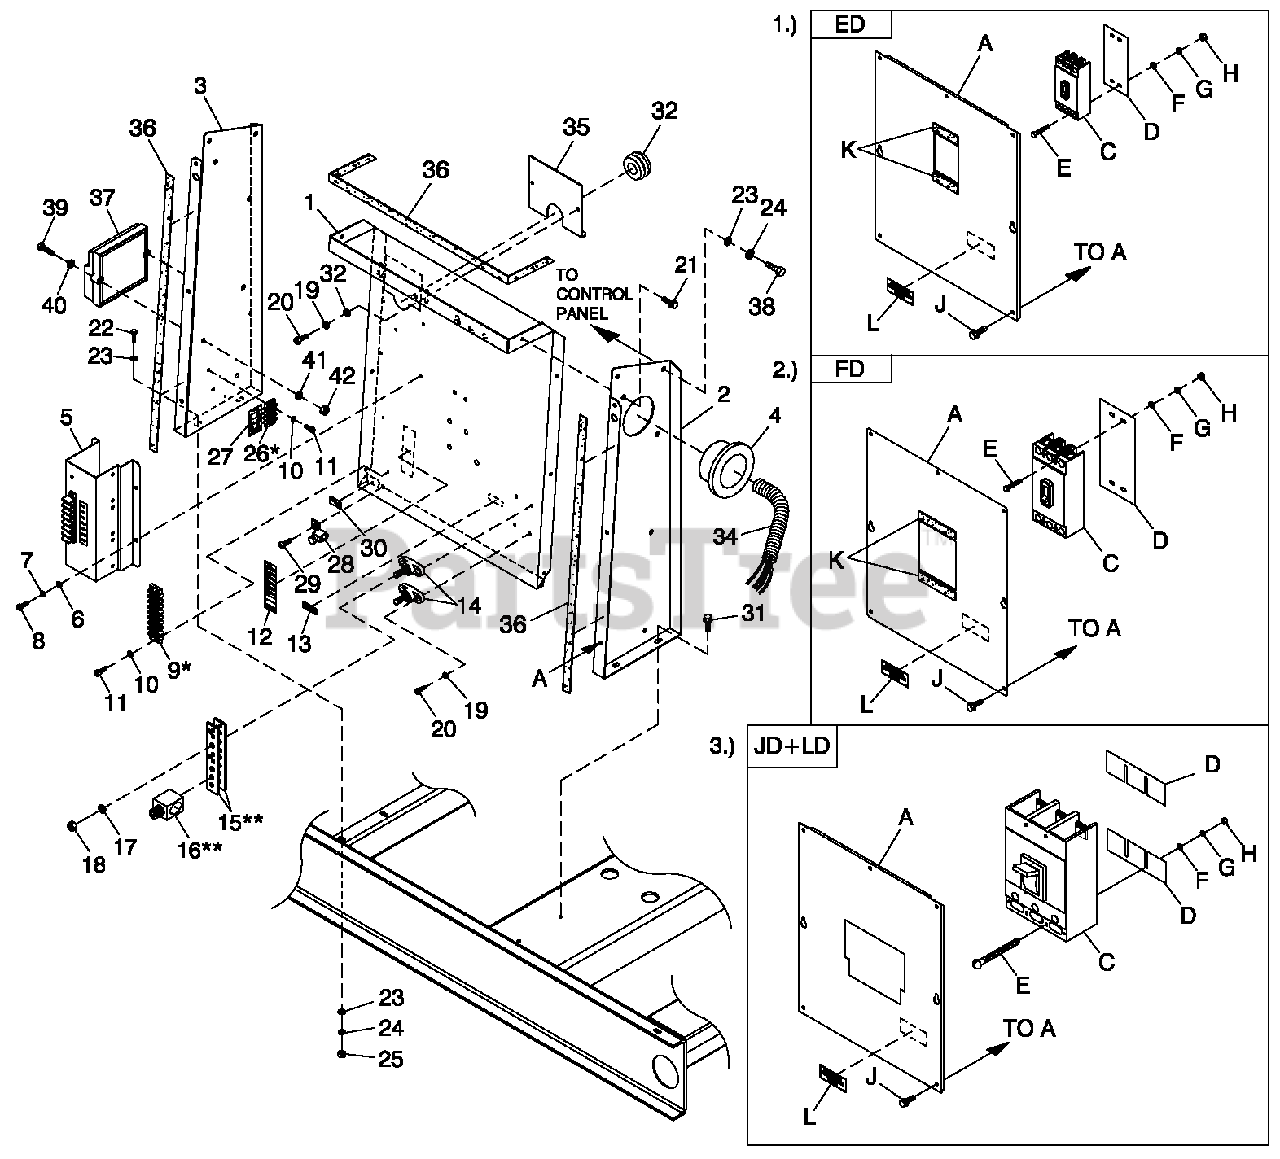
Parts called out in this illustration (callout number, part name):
1	PAN CB CONN BOX
1	UL CIRCUIT BREAKER (ED)
2	STAND RH CONTROL
2	UL CIRCUIT BREAKER (FD)
3	STAND LH CONTROL
3	UL CIRCUIT BREAKER (JD+LD)
4	BUSHING SNAP SB-2.5-31
5	ASSY PCB INTERFACE 1PH 240V
6	WASHER FLAT M4
7	WASHER LOCK #8-M4
8	SCREW PHTTM4-0.7X 10 ZYC
9	BLOCK TERM 2 0 A 8 X 6 X 1100V
10	WASHER LOC K #6
11	SCREW PHTT # 6 -32X1 /2 ZYC
12	DECAL CPL CUST CONN H CTRL
13	DECAL NEUTRAL
14	JUNCTION BLOCK 3/8-16
15	BUS BAR NEUTRAL BLOCK 390
16	LUG SLDLSS 600/250-1/0 X 1/4-28
17	WASHER LOCK 3/8
18	NUT HEX 3/8-16 STEEL
19	WASHER LOCK M5
20	SCREW PHTT M5-0.8X 16 ZYC
21	SCREW THF M6-1 X 16 N WA Z/JS
22	SCREW HHC M6-1.0 X 20 G8.8
23	WASHER FLAT 1/4-M6 ZINC
24	WASHER LOCK M6-1/4
25	NUT HEX M6X 1.0 G8YEL CHR
26	BLOCK TERM 2 0 A 6 X 3 X 1100 V
27	DECAL CUST CONN 120V UTILITY
28	LUG SLDLSS #6-14X 13/64CU
29	SCREW HHTT #10-32X3/8 CZ
30	DECAL GROUND LUG
31	SCREW HHTT M6-1.0X 16 ZYC
32	WASHER FLAT M5
33	GROMMET 1.25X .25X .75
34	CONDUIT FLEX 2.0" ID
35	PLATE WIRE SNGLGALV
36	TAPE ELEC 1/2 FOAM (AS REQ'D)
37	ASSY PCB HSB CTRL IGN MODULE
38	SCREW HHC M6-1.0 X 16 G8.8
39	SCREW PPHM # 10 /32X 2
40	WASHER FLAT #10 ZINC
41	WASHER LOCK #10
42	NUT HEX #10-32 STEEL
A	COVER ED CB STAND C3
C	CB0090A3P 480V S ED 4 LL
D	INSULATOR C BS(ED-3P)
E	SCREW RHM #10-32X4-1/2
F	WASHER FLAT #10 ZINC
G	WASHER LOCK #10
H	NUT HEX #10-32 STEEL
J	SCREW THF M6-1 X 16 N WA Z/JS
K	TAPE ELEC 1/2 FOAM (AS REQ'D)
L	DECAL CUSTOMER CONNECT INSIDE
A	COVER FDCB STAND C3
C	CB 0200A 3P 600V S FD6 LL
D	INSULATOR CB FD FRAME 30MIL
E	SCREW SHC 1/4-20 X 4 G8.8NZ
F	WASHER FLAT 1/4-M6 ZINC
G	WASHER LOCK M6-1/4
H	NUT HEX 1/4-20 STEEL
J	SCREW T H FM 6 -1 X 16 NWAZ/JS
A	COVER JD/LDCB STAND C3
C	CB0300A3P 600VS JD 6 LL
D	INSULATOR CIRCUIT BR. JD/LD
E	SCREW RHM 1/4-2 0X3
